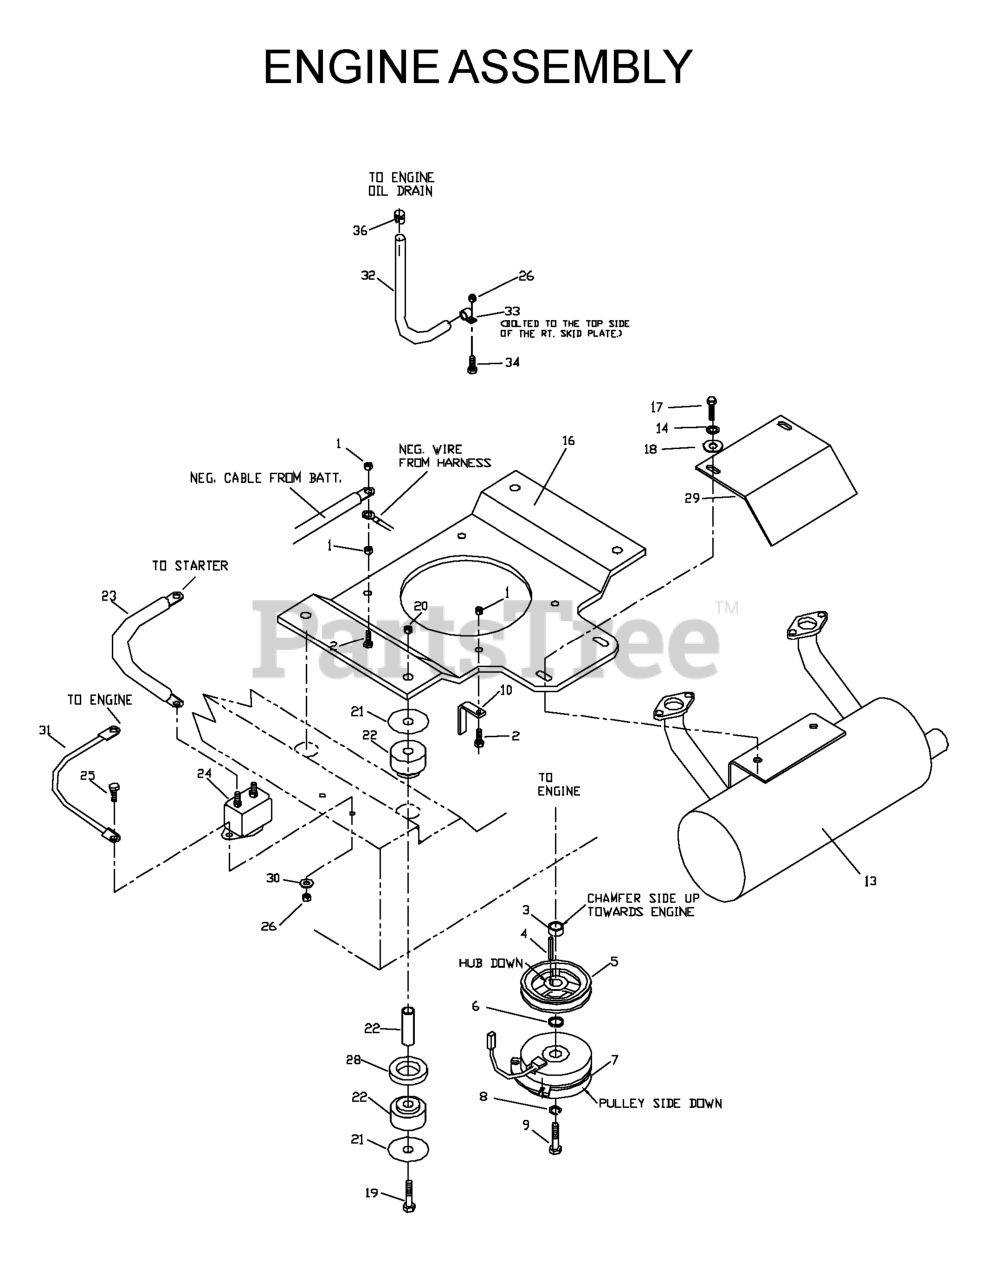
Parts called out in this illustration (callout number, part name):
1	NUT 5/16C CENTERLOCK
2	HCS 5/16C X 1 3/4
3	SPACER .70"
4	KEY 1/4 SQ X 1.0
6	SPACER .508"
7	ELECTRIC CLUTCH W/CABLE
8	WASHER 7/16 LOCK
9	BOLT 7/16F X 2 1/2
10	CLUTCH TIE DOWN
12	KAW PIGTAIL
13	MUFFLER KAWASAKI GEN II
14	WASHER.LOCK.HVY.HLCL.SPR.5/16
17	HCS 5/16C X 3/4
18	WASHER 5/16 FLAT
19	HCS 1/2C X 3 1/4
20	NUT 1/2-13 HEX NYLOC ZD
21	ISOLATOR WASHER
23	CABLE POSITIVE
25	HCS 1/4C X 5/8
26	NUT 1/4C CENTER LOCK
27	ASM, KAWASAKI FUEL
28	ISOLATOR SPACER
29	MUFFLER GUARD
30	WASHER 1/4 INT TOOTH
31	GROUND WIRE (KAW)
32	OIL DRAIN HOSE (KAW)
34	HCS 1/4C X 3/4 HCS
